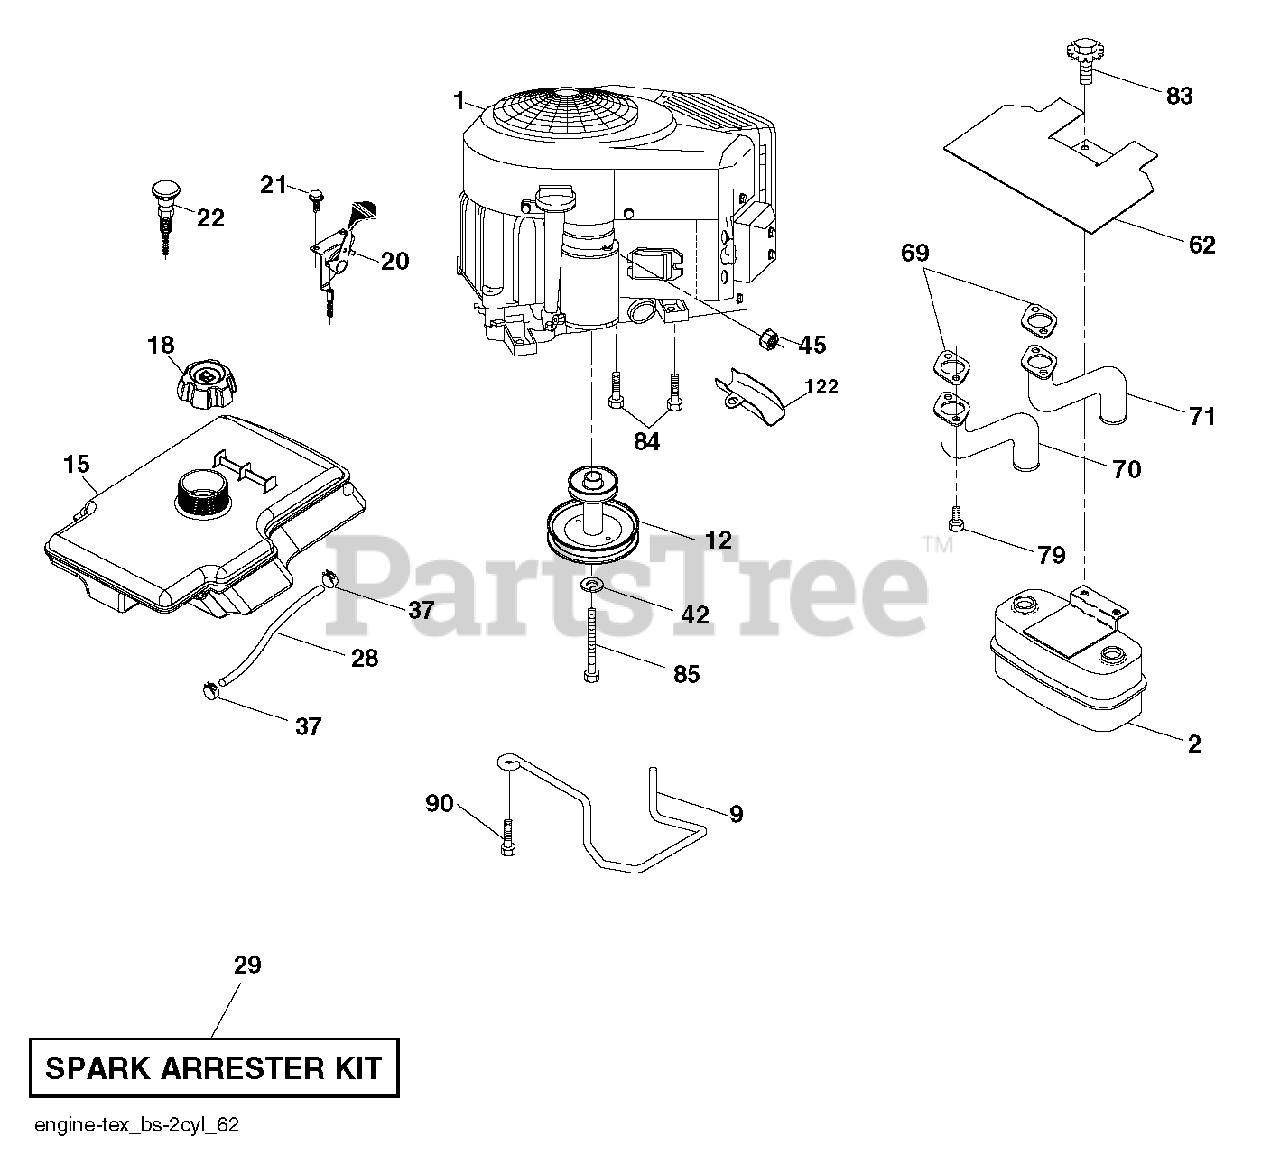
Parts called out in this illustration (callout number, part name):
2	MUFFLER.TWIN.CYL.LOW.TONE
9	KEEPER.BELT.ENGINE.4.2
12	PULLY ENGINE
18	CAP.ASM.FUEL.TANK.3"BLACK
20	THROTTLE CABLE
21	SCREW.#10 X 0.750.BOS THREAD
22	CONTROL CHOKE
29	ARRESTER SPARK (OPTIONAL)
37	HOSE CLAMP
42	LOCKWASHER
45	NUT
62	RP SHIELD HEAT MUFFLER
69	GASKET.MUFFLER
70	TUBE MANIFOLD LH
71	EXHAUST TUBE RH
79	SCREW.SOCKET.HEAD.5/16-18
83	BOLT, 5/16-18 X 1 3/4
84	SCREW.3/8-16
85	BOLT HEX 7/16-20X4-1/4"
90	SCREW 3/8-16X1
122	EXTENSION DRAIN OIL
